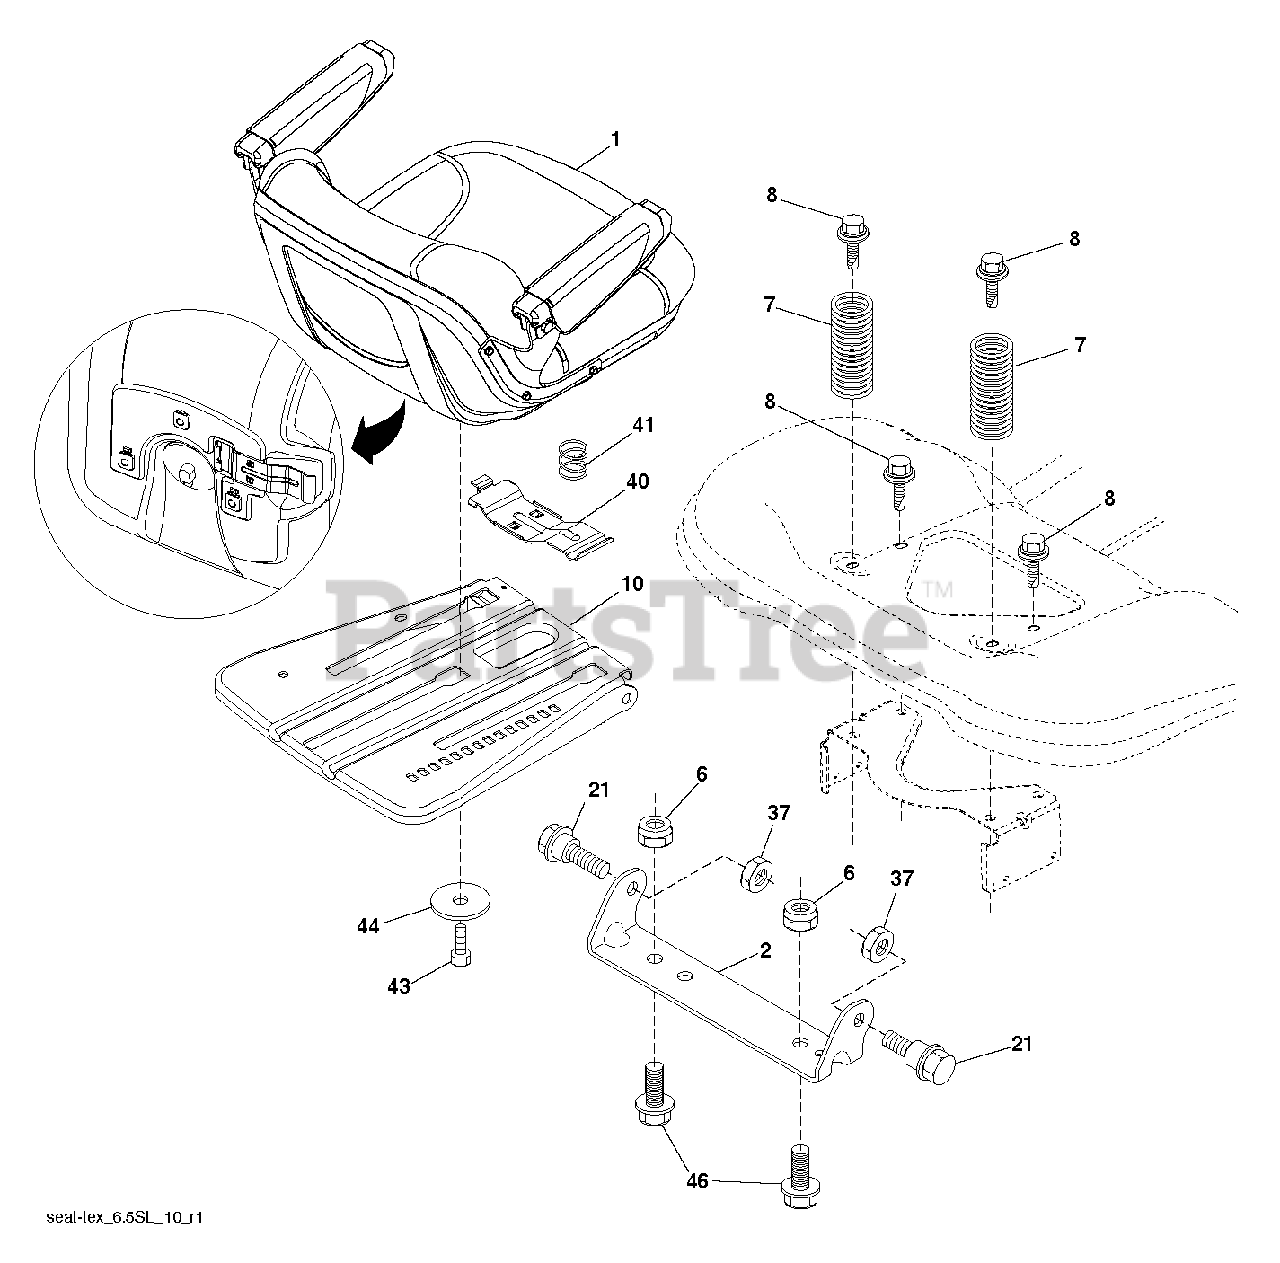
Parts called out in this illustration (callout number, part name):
1	SEAT.TH154.GREY.HUS.ARMREST
2	BRKT.PIVOT.FENDER
6	NUT
7	SPRING.COMPRESSION.SEAT.BLACK
8	BOLT, 5/16-18 X 1 3/4
10	PAN.ASM.SEAT.3PT
21	BOLT.5/16-18X5/8.SHOULDER
37	NUT.71038.31-18.HEX.NYLOCK
40	HANDLE.SLIDE.SEAT.TEX.GREY
41	SPRING.LATCH.SEAT.TEX
44	WASHER 13/32 X 2-3/8 X 12GA
46	BOLT.3/8-16X1;1.25OD.WSHR.SEMS
